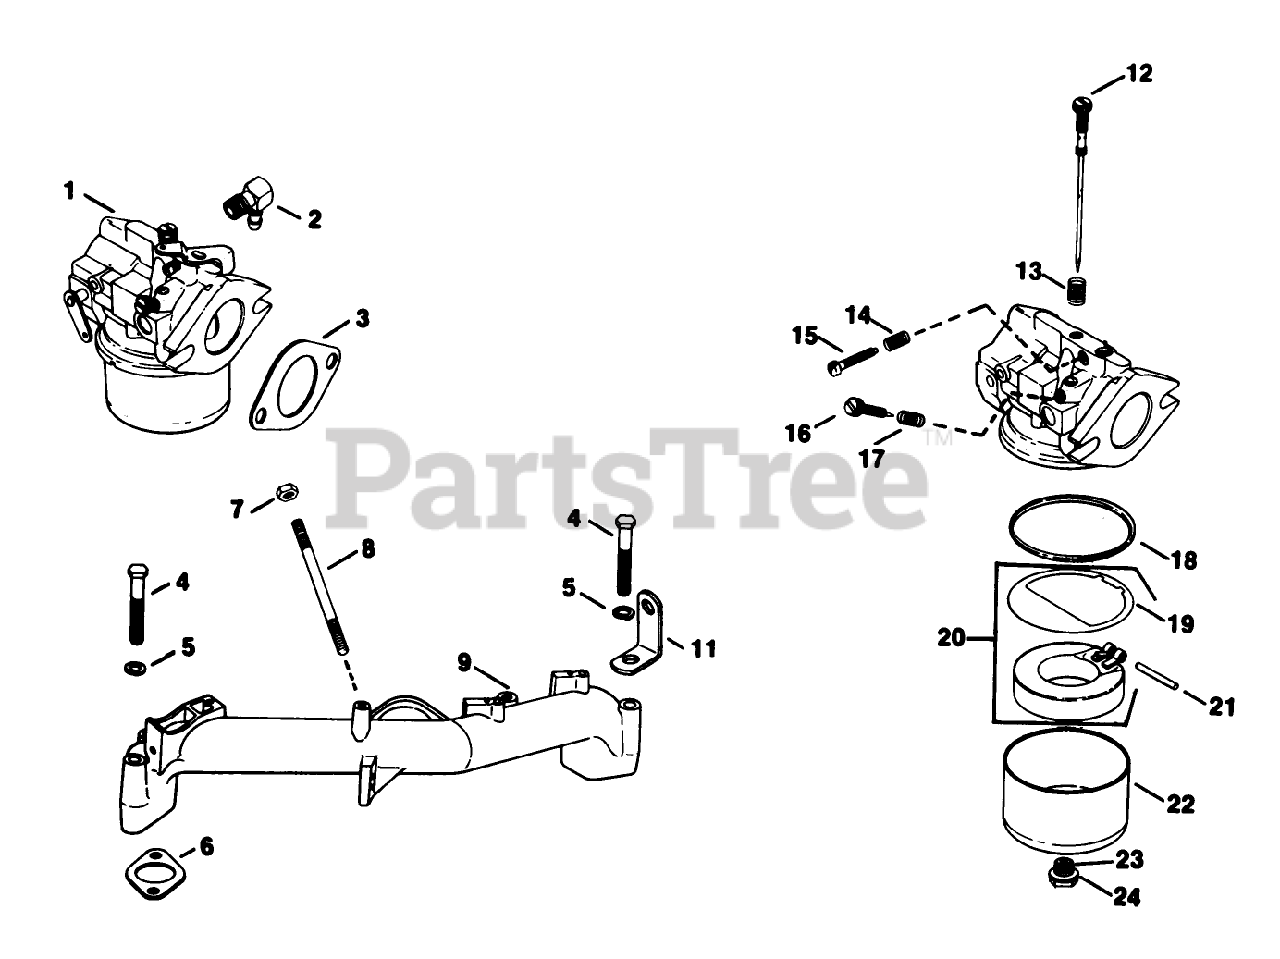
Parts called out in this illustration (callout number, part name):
1	Carburetor Assembly
2	Connector-90?
3	Gasket
4	Screw-H.C.
5	Washer
6	Gasket-Intake
9	Manifold-Intake
11	Strap-Lifting
12	Needle-Main Fuel Adj.
13	Spring-Main
14	Spring-Idle Speed
15	Screw
16	Needle-Idle Adj.
17	Spring-Idle
18	Gasket-Bowl
19	Gasket-Bowl Baffle
20	Kit-Float
21	Pin-Float Hinge
22	Bowl
23	Screw-Bowl Retainer
24	Gasket-Bowl Screw
